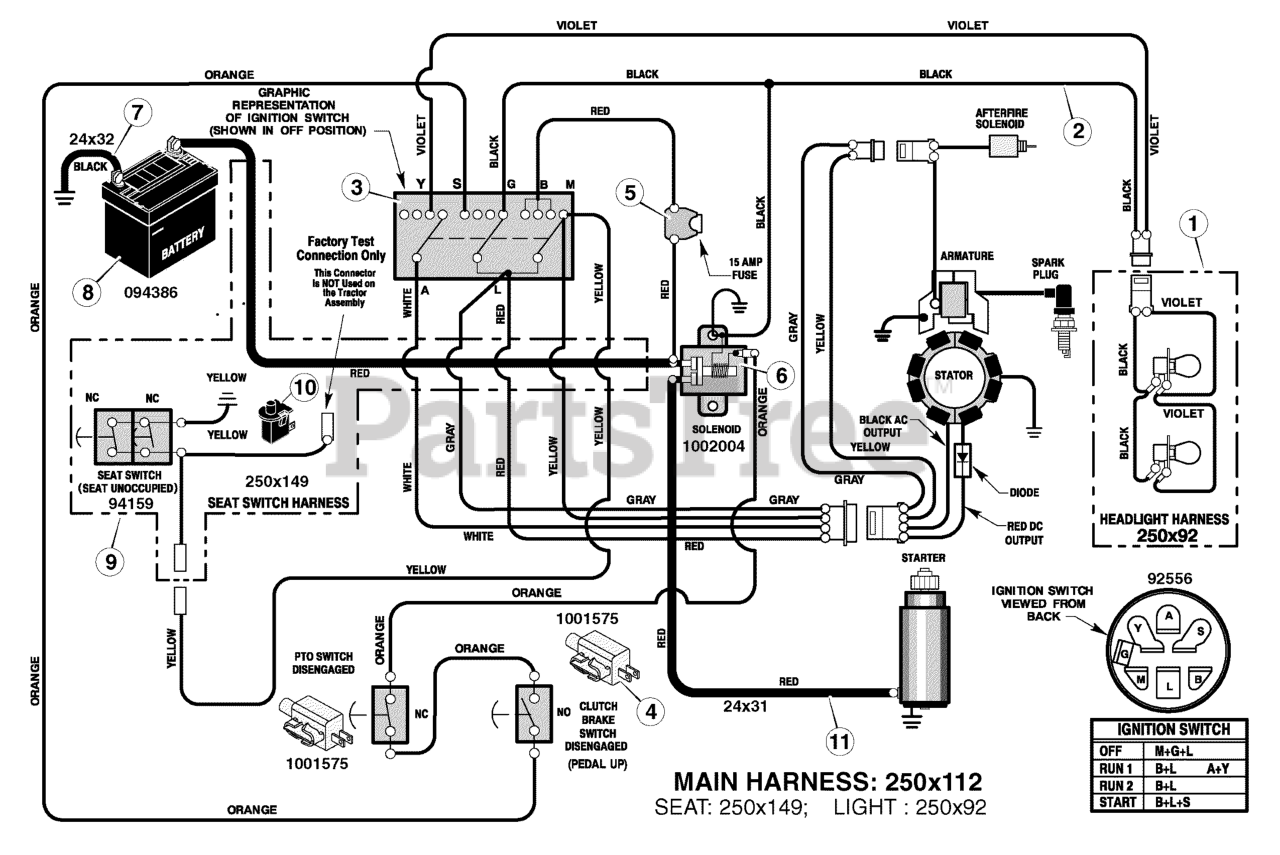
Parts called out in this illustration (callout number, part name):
1	Harness, Light Wire
1	Socket, Light
1	Bulb, Light
2	Harness, Chassis Wire
3	Switch, Ignition
3	Key, Ignition
3	Nut, Hex
3	Cap, Ignition
4	Switch, Limit
5	Holder, Fuse
6	Solenoid
6	Screw, Mounting
6	Locknut
7	Cable, Battery Ground
7	Screw, Ground Cable
8	Battery
8	Bolt, Carriage
8	Wingnut
8	BOOT, Battery Terminal, Positive
9	Harness, Seat Switch Wire
10	Switch, Seat Sensor
